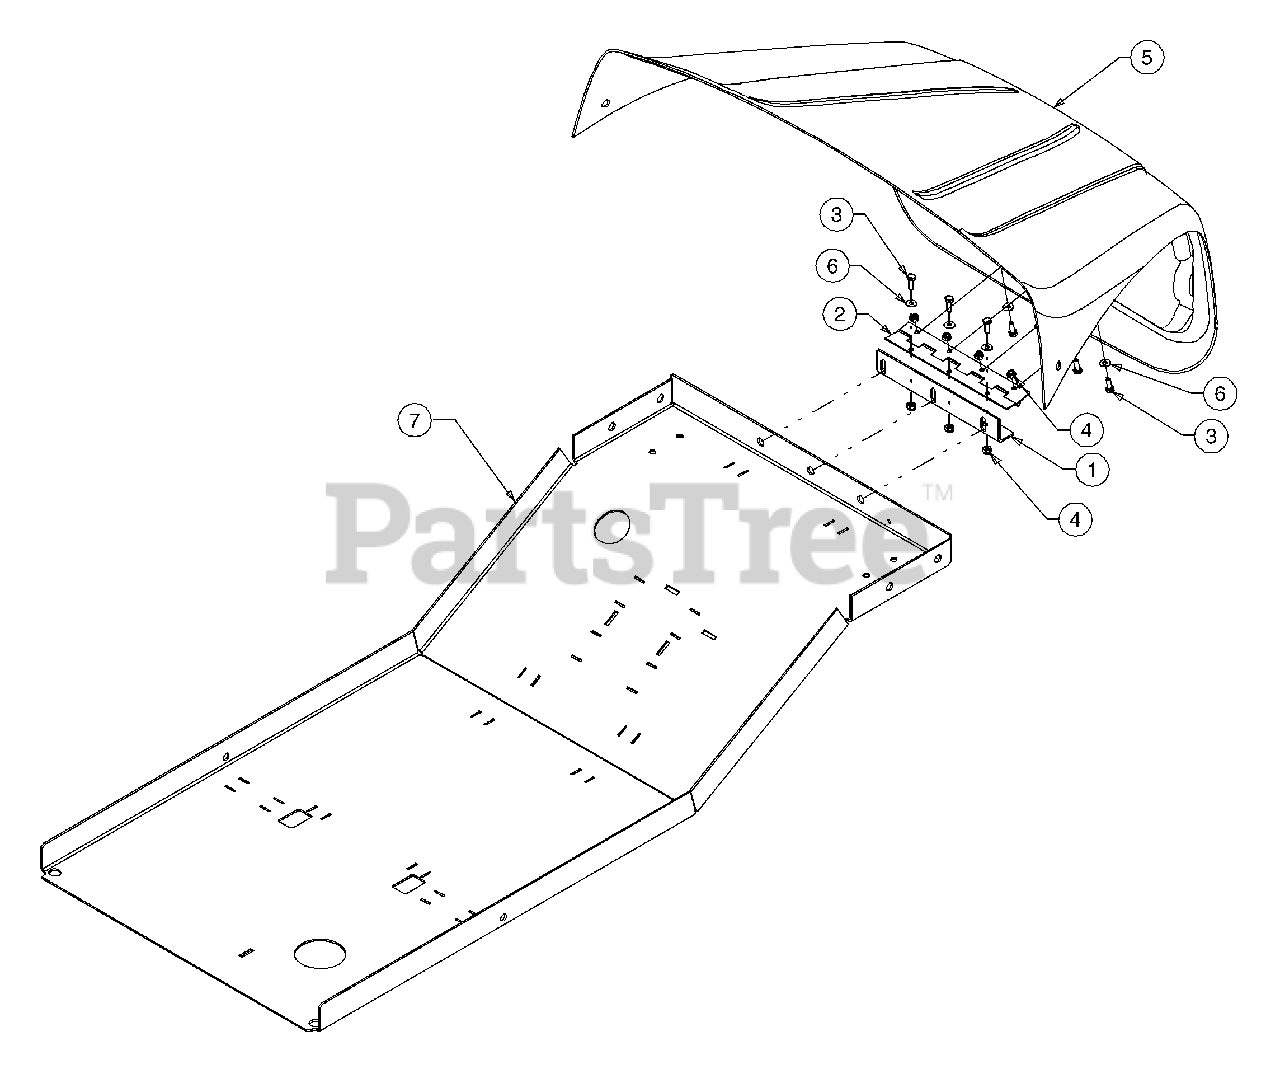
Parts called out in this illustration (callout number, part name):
3	Hex Screw, 1/4-20, .75, Gr5
4	Nut, Nylon Hex Lock, 1/4-20, Gr8
5	Panel, Hood
6	Washer, Flat, .271 x .630 x .065
7	Frame, Lower Front
